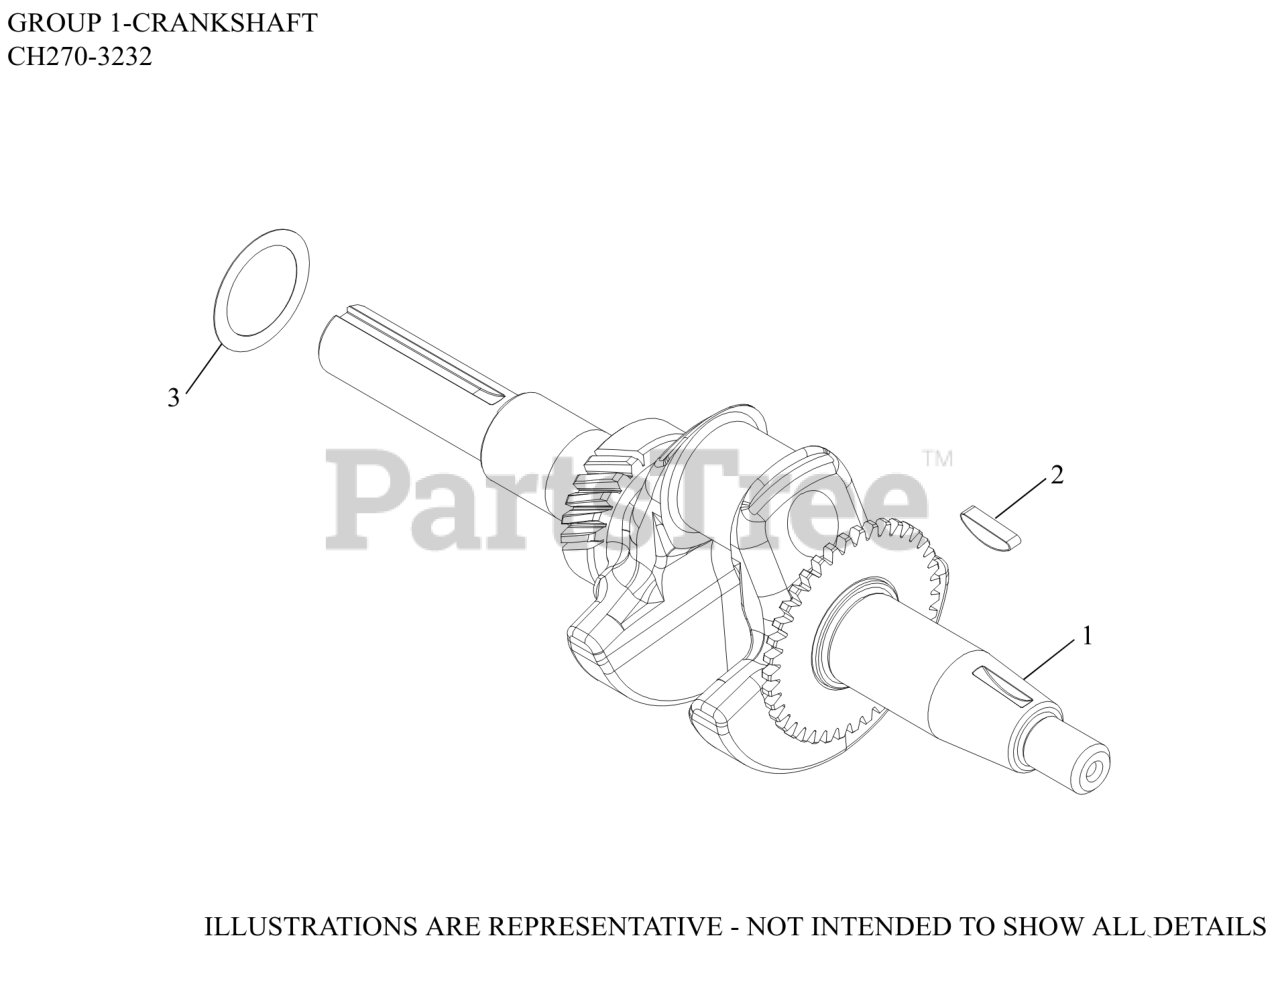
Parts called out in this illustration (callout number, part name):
1	CRANKSHAFT ASSEMBLY
2	KEY, FLYWHEEL
3	KIT, THRUST SHIM
